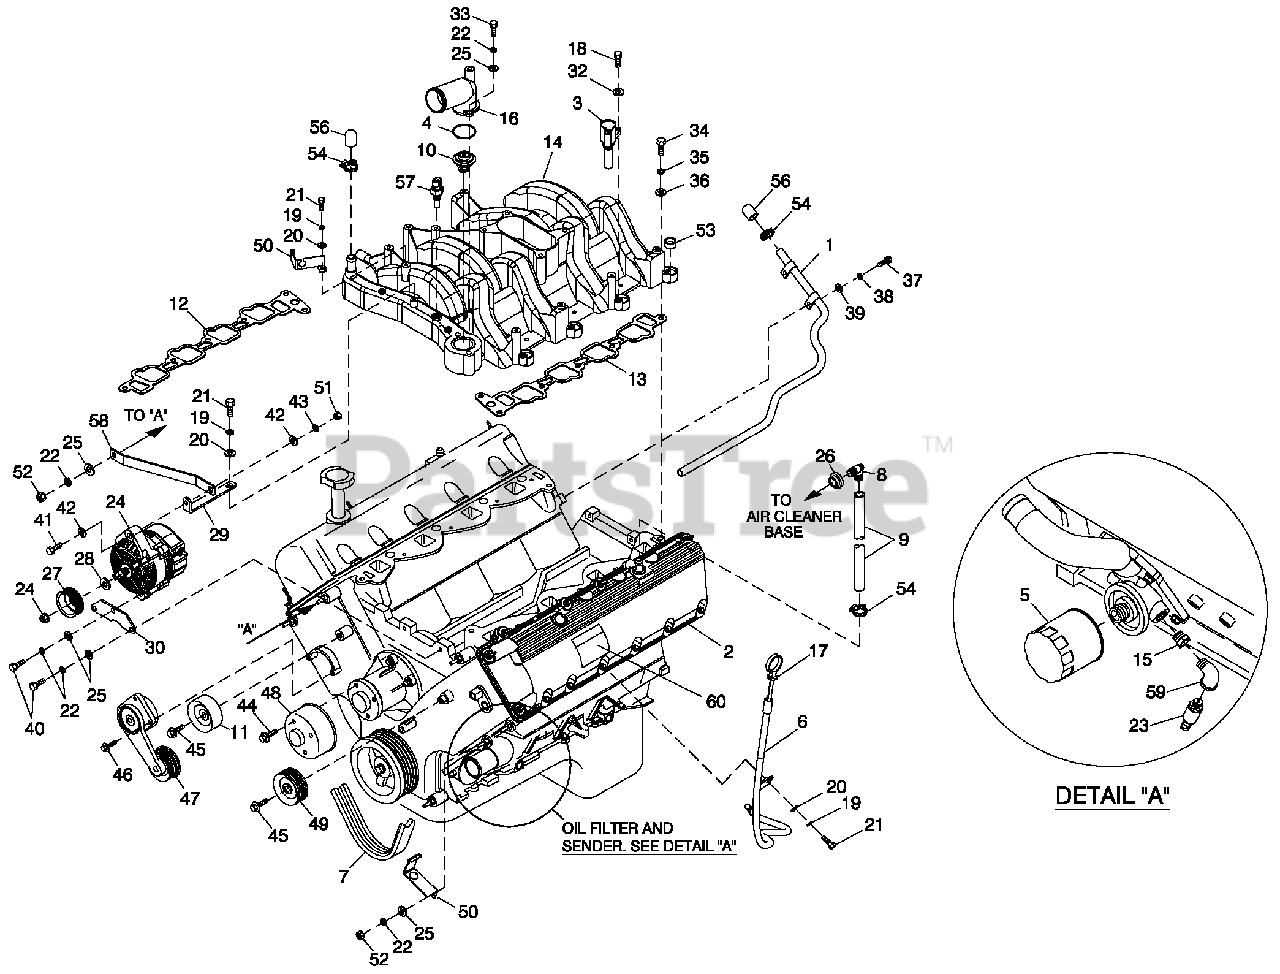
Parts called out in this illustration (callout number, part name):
1	TUBE HEATER WATER
2	ENGINE 5.4L FORD
3	IGNITION COIL ASSY FORD
4	GASKET THERMOSTAT HOUSING FORD
5	OIL FILTER FORD V-10 ENGINE
6	TUBE OIL LEVEL INDICATOR FORD
7	BELT SERPENTINE 65.0" (1800 RPM)
8	BARBED EL 90 3/4 PLASTIC
9	HOSE 3/4 ID SAE-30R2 (16.75" LG)
10	THERMOSTAT ASSY FORD
11	PULLEY FAN BELT FORD
12	GASKET INTAKE MANIFOLD RIGHT
13	GASKET INTAKE MANIFOLD LEFT
14	INTAKE MANIFOLD 5.4L (PLASTIC)
15	BSHG RDCRHEX1/4 TO 1/8
16	CONNECTION WATER OUTLET FORD
17	REWORK DIPSTICK 5.4L 27.75"
18	SCREW HHC M5-0.8X 25 G8.8
19	WASHER LOCK M6-1/4
20	WASHER FLAT 1/4 ZINC
21	SCREW HHC M6-1.0X 20 G8.8
22	WASHER LOCK M8-5/16
23	SENDER OIL PRESSURE 1/8&NPT
24	ALTERNATOR DC W/OUT PULLEY
25	WASHER FLAT 5/16 ZINC
26	GROMMET
27	PULLEY 80 OD DC ALTERNATOR (1800RPM)
28	SPACER DC ALTERNATOR PULLEY
29	BRKT DC ALTERNATOR UPPER
30	BRKT DC ALTERNATOR LOWER
31	HARN ENG 5.4L H-100 (USE WITH PROBE P/N 0E2507)
32	WASHER FLAT M5
33	SCREW HHC M8-1.25X 90 G8.8
34	SCREW HHC M8-1.25X 50 G8.8
35	WASHER LOCK M8-5/16
36	WASHER FLAT 5/16-M8 ZINC
37	SCREW HHCM10-1.5X20 G8.8
38	WASHER LOCK M10
39	WASHER FLAT 3/8-M10 ZINC
40	SCREW HHC M8-1.25X 20 G8.8
41	SCREW HHC M10-1.5 X 45 G8.8 FT
42	WASHER FLAT 3/8-M10 ZINC
43	WASHER LOCK M10
44	SCREW WP PULLEY M8-1.25X 19
45	BOLT HEX FL HD M8-1.25X 28
46	BOLT HEX FL HD M8-1.25X 31
47	TENSIONER ENG. AUTOMATIC BELT
48	PULLEY WATER PUMP FORD (1800RPM)
49	PULLEY GROOVED ENGINE IDLER
50	BRACKET SIGNAL CONDITIONER
51	NUT HEX M10-1.5 G8YEL CHR
52	NUT HEX M8-1.25 G8YEL CHR
53	PLUG EXPANSION 14 OD
54	CLAMP HOSE#10.56-1.06
56	CAP RUBBER
57	TEMPERATURE SENDER, DELPHI
58	BRACKET DC ALT STABILIZER
59	ELBOW 90D STREET 1/8
60	DECAL EPA STATIONARY EMERGENCY
